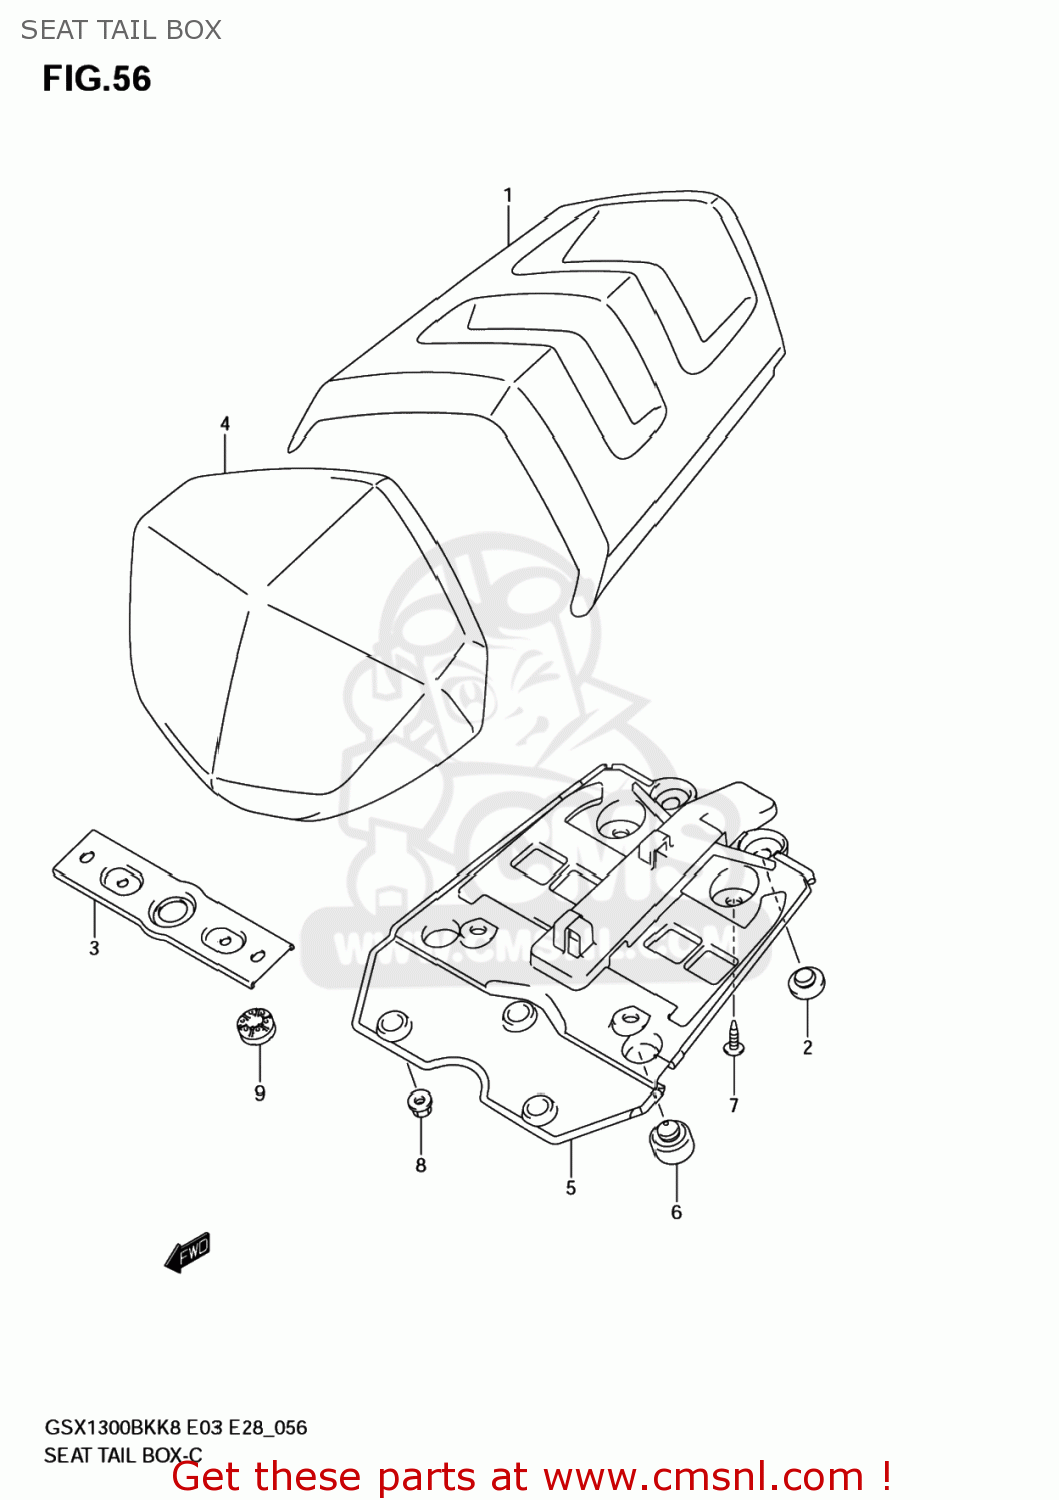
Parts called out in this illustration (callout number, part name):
1	BOX,SEAT TAIL
2	CUSHION,SEAT
3	STRIKER,SEAT LOCK
4	BACKREST,PILLION SEAT
5	BOTTOM,SEAT TAIL BOX
6	CUSHION
7	SCREW
8	NUT
9	CUSHION,SEAT LOCK(10X22X6)
